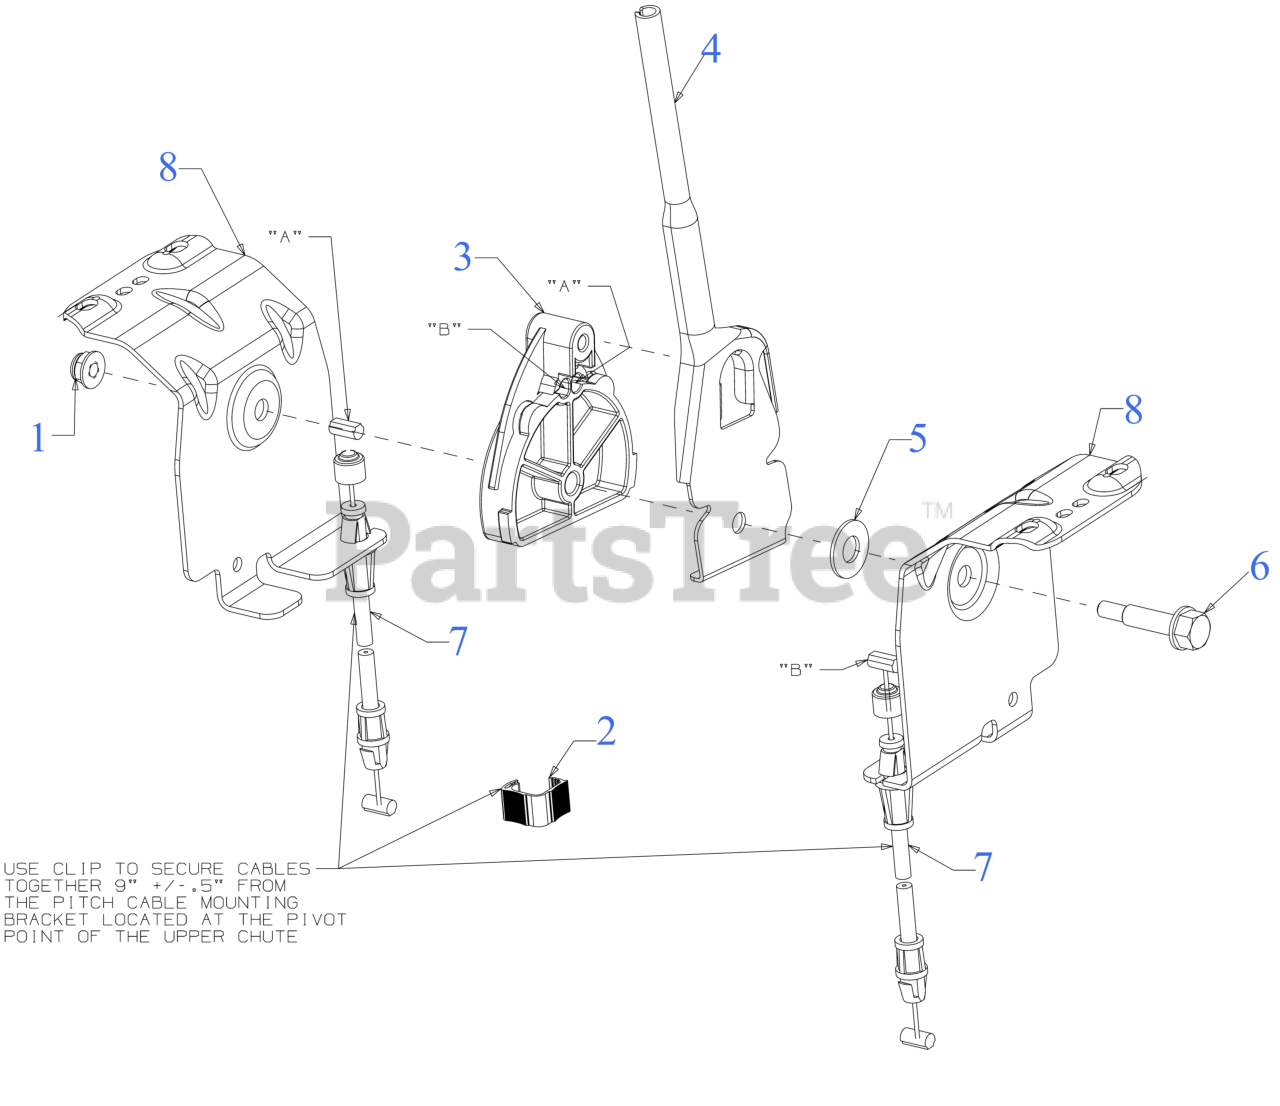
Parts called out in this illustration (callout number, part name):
1	FLANGE LOCK NUT
2	CABLE CLIP
3	CABLE GUIDE
4	SHIFT LEVER
5	FLAT WASHER
6	SHOULDER SCREW
7	2-WAY PITCH CONTROL CABLE
